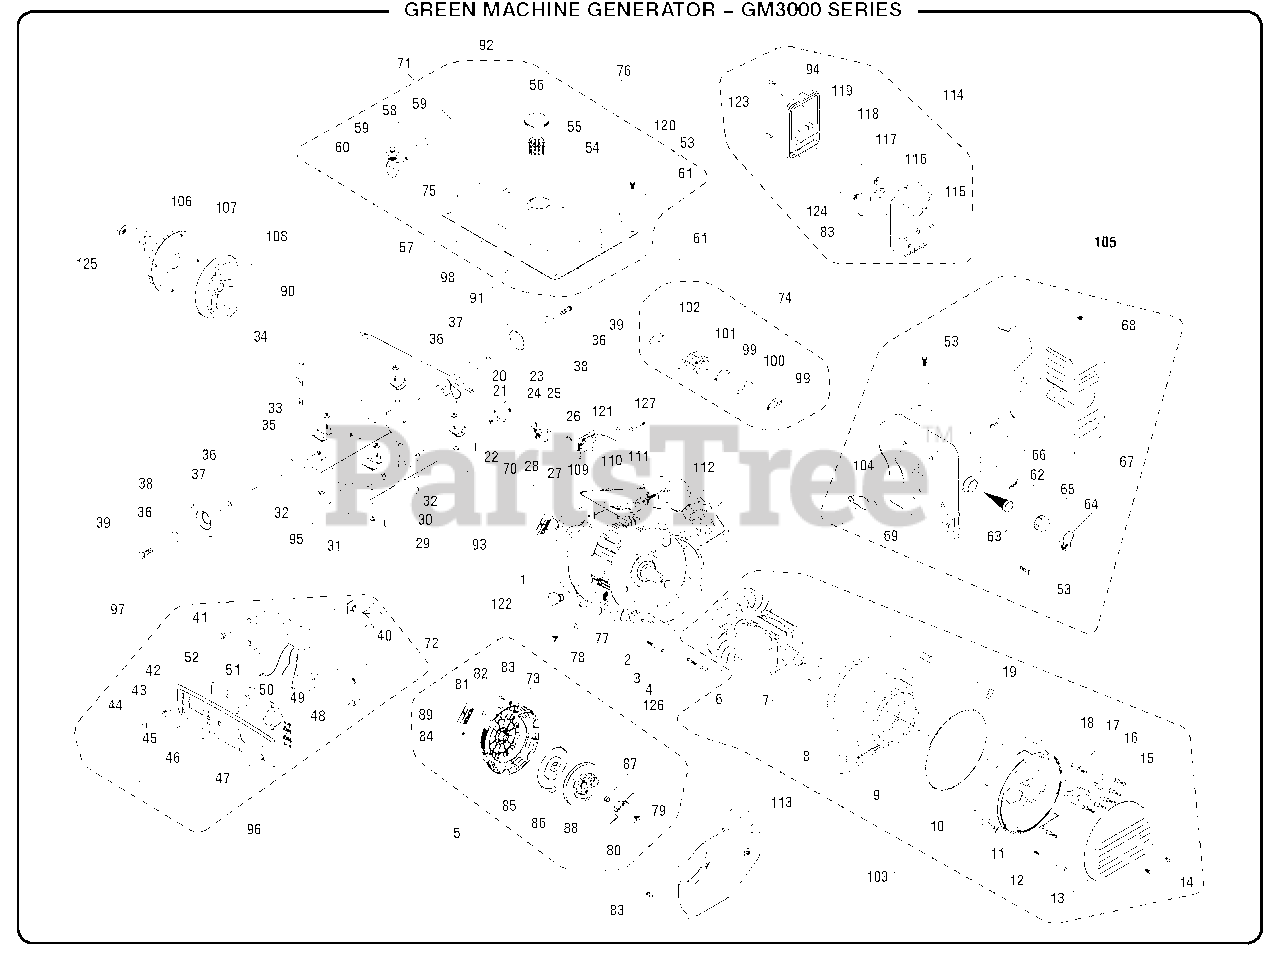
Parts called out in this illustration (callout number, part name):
1	Engine SPE195 (Incl. Key Nos. 77-78 and 109-112)
2	Bolt (M8 x 35 mm)
3	Bolt (M6 x 12 mm)
4	Lock Washer
5	Recoil Starter Assembly (Incl. Key Nos. 73 and 79-89)
6	Rotor Assembly
8	Stator Assembly
9	Stator Cover
10	Rear Frame
11	Wire Compressing Plate
12	Bolt (M6 x 103 mm)
13	Rear End Cover
14	Bolt (M6 x 10 mm)
15	Terminal Block
16	Screw (M5 x 14mm)
17	Lock Washer (M5)
18	Washer (M5)
22	Bolt (M8 x 40 mm)
23	Handle Stem Head
24	Lock Nut (M8)
26	Square Bolt
29	Screw (M8 x 40 mm)
30	Alternator Vibration Absorber
31	Combustion Warning Label
33	Engine Vibration Absorber
35	Lock Nut (M10 x 1-1/4 in.)
36	Wheel Bushing
37	Axis Cover
39	Bolt (M10 x 75 mm)
40	Control Box
41	Screw (M6 x 14 mm)
42	Control Panel
43	Choke Switch
44	Switch Jacket
45	Bolt (M3.5 x 9 mm)
46	Bolt (M3.9 x 9 mm)
47	Bolt (M4 x 8 mm)
48	120 V 20 Amp Receptacle
49	120 V 30 Amp Receptacle
50	AC Circuit Breaker (20 A)
51	AC Circuit Breaker (25 A)
52	4 in 1 Digital Meter
53	Bolt (M6 x 12 mm)
54	Fuel Tank
55	Fuel Filter
56	Fuel Tank Cap
57	CPSC Label (English/Spanish)
58	Fuel Hose
59	Fuel Hose Clip
60	Fuel Cock
61	Hot Surface Label
62	Muffler Screen
65	Muffler Screen Cover
66	Shockproof Bar
67	Muffler Cover
68	Bolt (M6 x 10 mm)
70	Locking Pin Label
71	Start Guide Label
72	Ground Label
73	Bushing Block
74	Carburetor Assembly (Incl. Key Nos. 99-102)
76	Fuel Tank Assembly Incl. Key Nos. 54-56, 58-61, 71, 75, 91, and 98)
77	Oil Filler Seal
78	Drain Plug (M10 x 1-1/4-16)
82	Starter Case
83	Screw (M6 x 12 mm)
84	Rope Clip
85	Starter Spring
86	Drum Sheave
88	Pawl Guide
89	Starter Handle
90	Fire Danger Label
91	Ground Warning Label
92	Oil Hangtag
93	Engine Shround Logo
94	Choke Label
95	Lubricant Label
96	Control Panel Label
97	Control Panel Assembly (Incl. Key Nos. 40-52)
98	Logo Label
101	Carburetor
103	Alternator Assembly (Incl. Key Nos. 6-19)
104	Exhaust Gasket
105	Muffler Assembly (Incl. Key Nos. 53, 62-69, and 104)
106	Starting Hub
109	Governor Arm
111	Carburetor Spring
114	Air Cleaner Assembly (Incl. Key Nos. 115-119)
115	Air Filter Case
117	Element Fitting Plate
118	Air Filter Element
119	Air Filter Cover
120	Warning Label
121	Screw (M6 x 20 mm)
122	Oil Cap/Dipstick
123	Screw (M6 x 12 mm, Fillister Hd.)
125	Nut (M16, Flange Hd.)
127	Ignition Module
